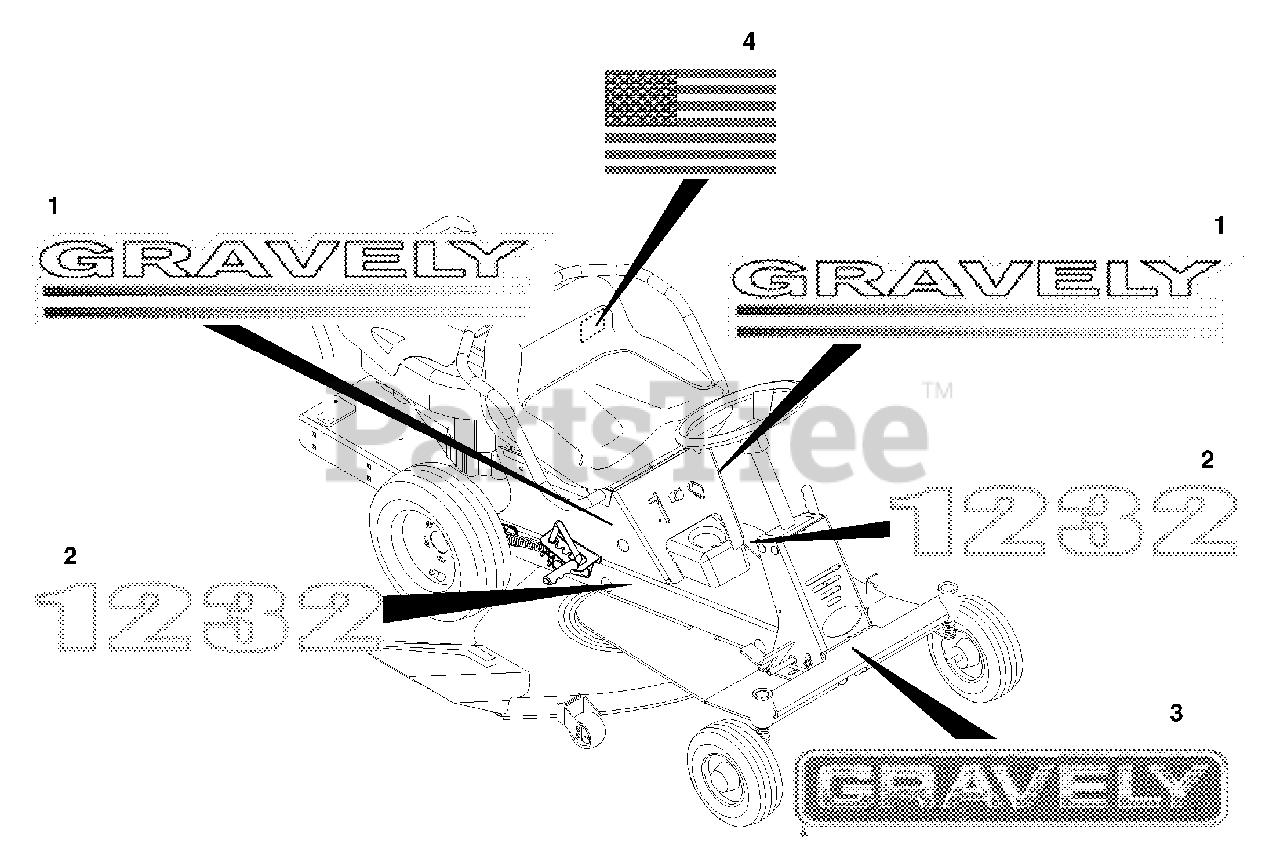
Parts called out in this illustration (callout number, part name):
1	Decal, Gravely ZT
2	Decal, Rear Engine Rider Gravely 1232 (062)
2	Decal, Rear Engine Rider Gravely 1028 (060)
2	Decal, Rear Engine Rider Gravely 1440 (064)
3	Decal, Gravely
4	Decal, American Flag
